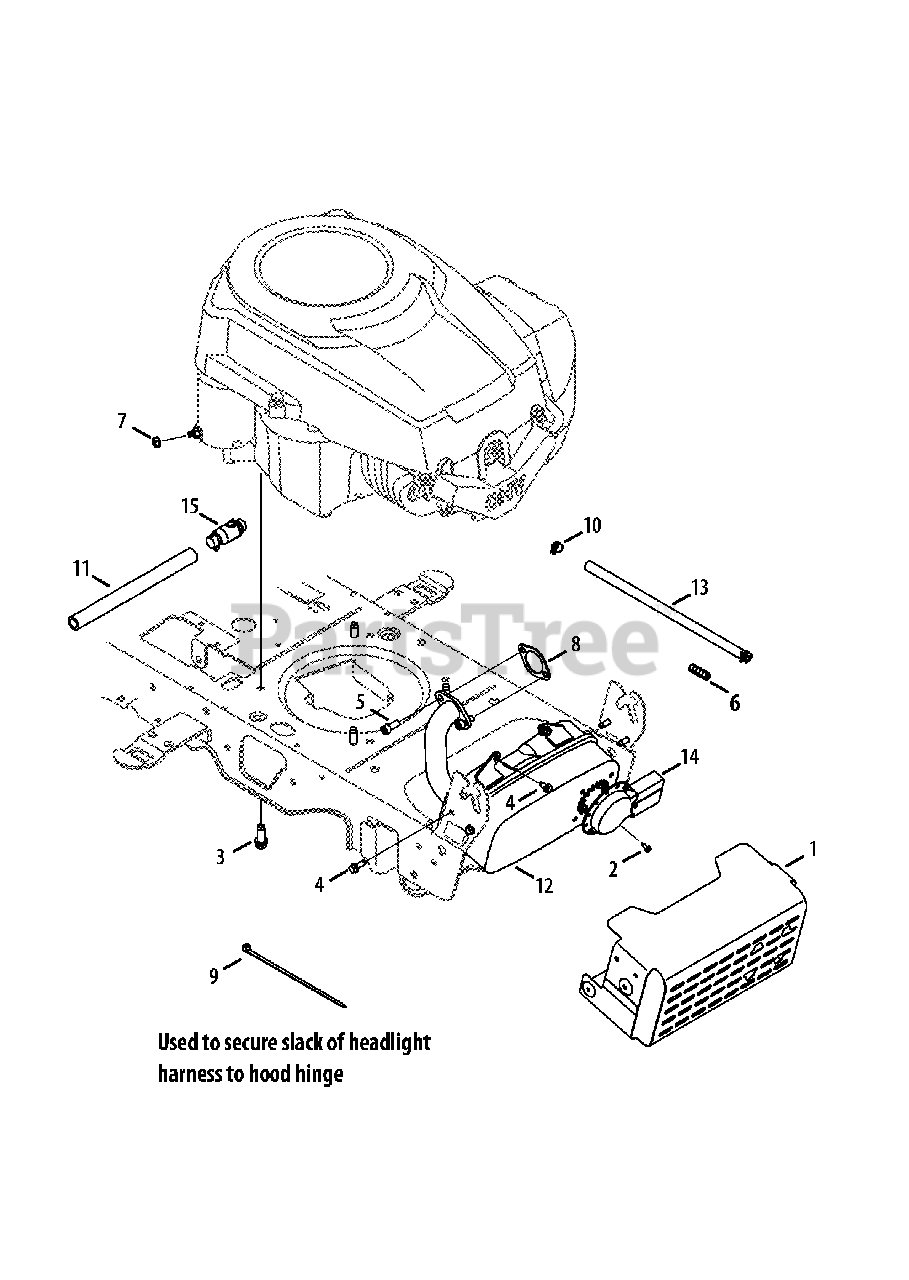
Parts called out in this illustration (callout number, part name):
1	Shield Ass’y, Muffler
2	Screw, Ab, #8-18, 0.500,
3	Screw, Self-tapping, 3/8-16, 1.000,
4	Screw, Self-tapping, 1/4-20, 0.500,
5	Screw, Socket Head, 5/16-18, .750
7	Nut, Sems, 1/4-20
8	Gasket, Exhaust
9	Cable, Tie, 3/16 x .05 x 7.4
10	Clamp, Hose, .490 Dia.
11	Hose, Extension, Oil Drain
12	Muffler, Single, Kohler
13	Hose, Fuel, Low Permeation, 1/4
14	Deflector, Muffler, Long
